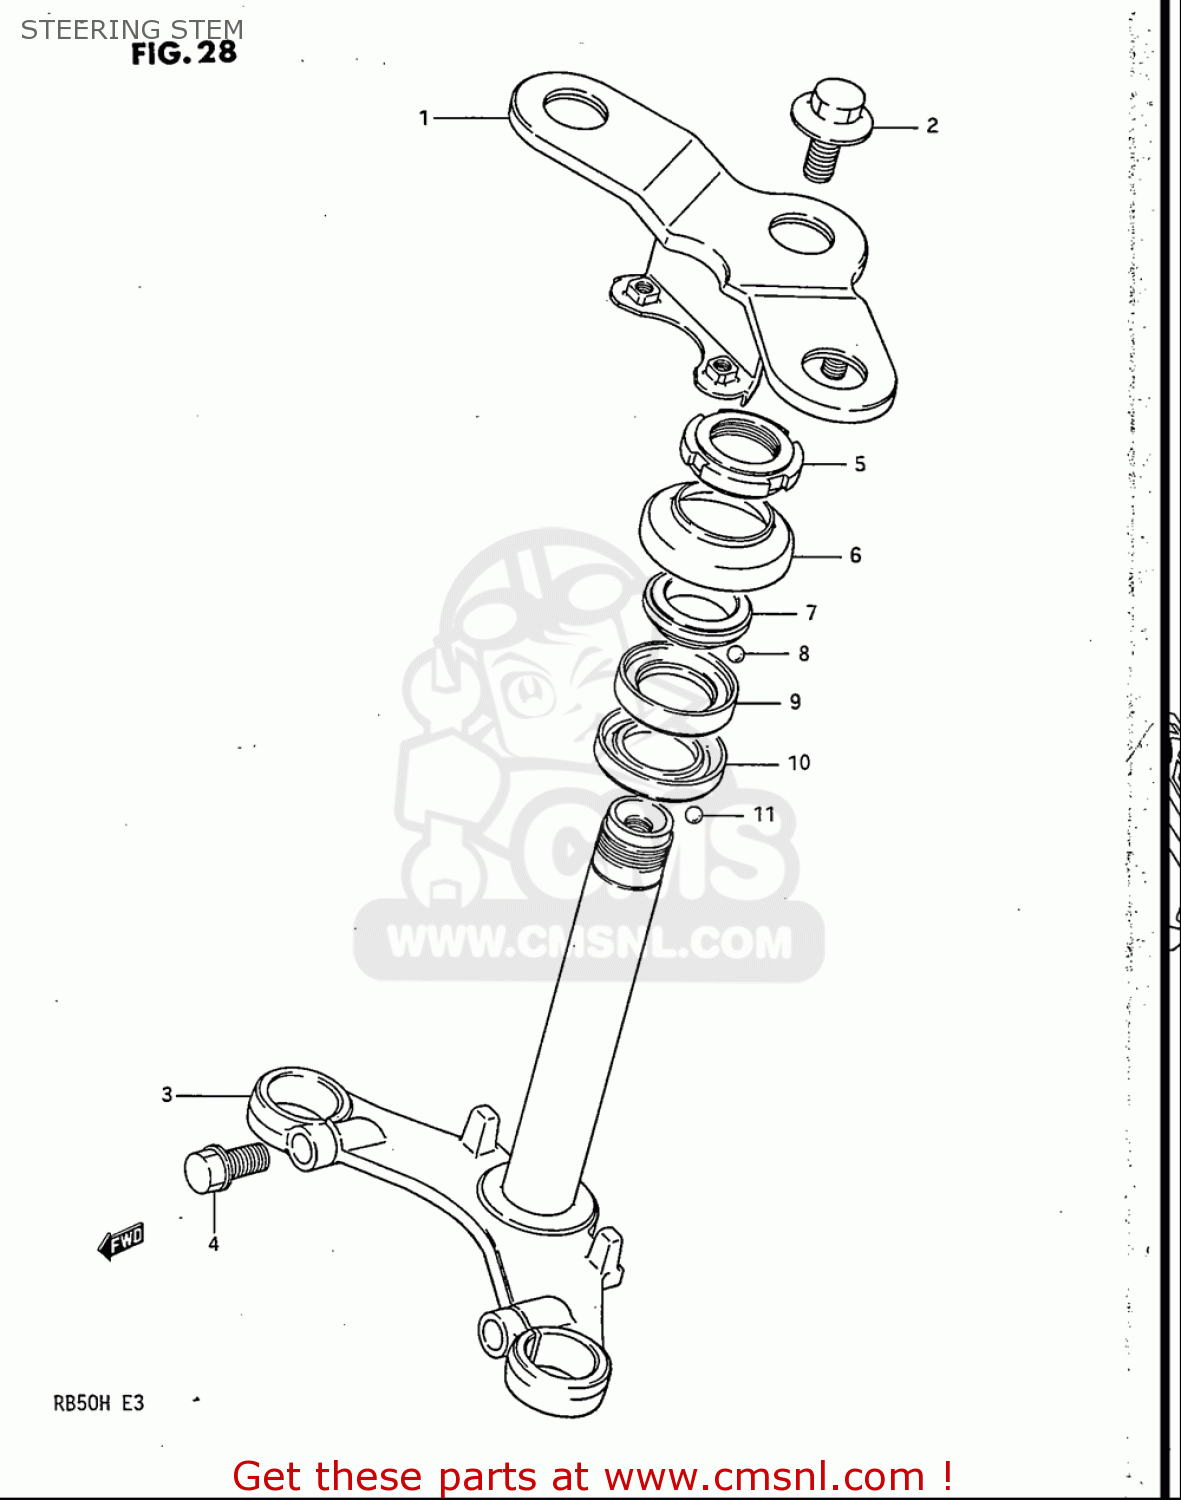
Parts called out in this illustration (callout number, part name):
1	HEAD,STEERING STEM
4	BOLT
5	NUT,STEERING STEM(25X44X10)
7	RACE,STEERING OUTER UPR
8	BALL
9	RACE,STEERING INNER UPR
10	LACE,STEERING INNER LWR
11	BALL
